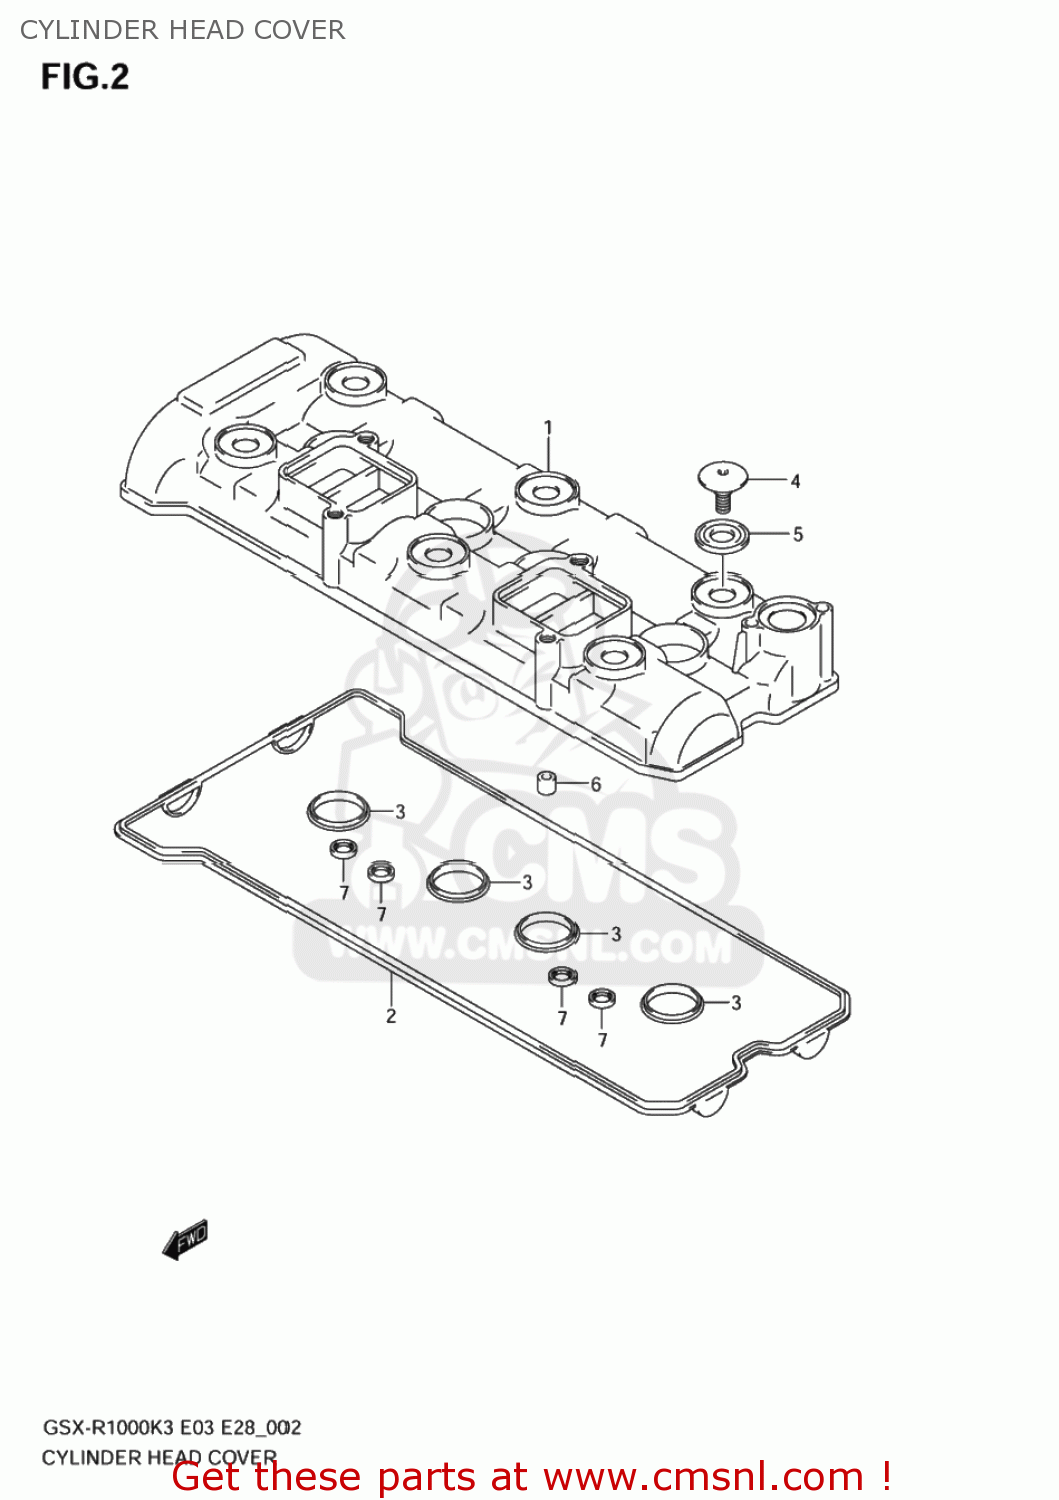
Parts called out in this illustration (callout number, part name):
1	COVER,CYLINDER HEAD
2	GASKET,CYL HEAD COVER NO.1 (NAS)
3	GASKET,CYL HEAD COVER NO.2
4	BOLT(7X17.5)
5	WASHER(10.6X25.5X2.3)
6	PIN(6.2X8X16)
7	GASKET,2ND AIR PASSAGE (NAS)
